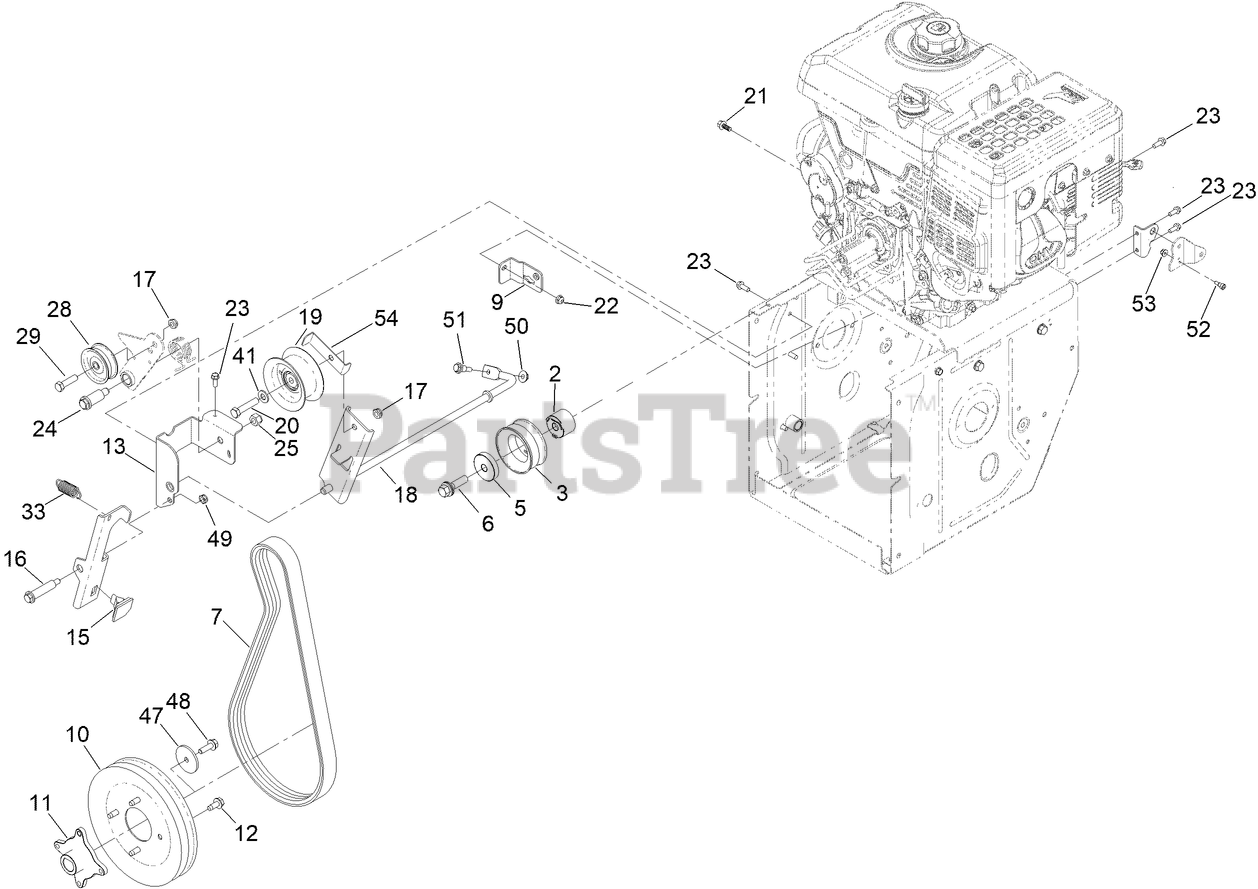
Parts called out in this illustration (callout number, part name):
2	PULLEY-SPACER
3	PULLEY-IMPELLER, DOUBLE SHEAVE
5	SUPPORT-PULLEY
6	BOLT-BLADE
7	BELT-V
9	BRACKET-CLUTCH, IMPELLER
10	PULLEY-IMPELLER, DOUBLE SHEAVE
11	HUB-PULLEY
12	SCREW-HWHTF
13	BRACKET-BRAKE, CLUTCH
15	PAD-BRAKE
16	BOLT-SHOULDER
17	NUT-HEX
18	IMPELLER CLUTCH ARM ASSEMBLY
19	PULLEY, IDLER
20	SCREW-HH
21	SCREW-HHF
22	NUT-HF
23	SCREW-HWH
24	BOLT-SHOULDER
25	NUT-HEX
28	PULLEY-IDLER
29	SCREW-HH
33	SPRING-EXTENSION
41	WASHER-FLAT
47	WASHER-PLAIN
48	SCREW-HHF
49	NUT-HEX
50	NUT-HF
51	BOLT-SHOULDER
52	SCREW-SHOULDER
53	NUT-HF
54	STOP-ARM
